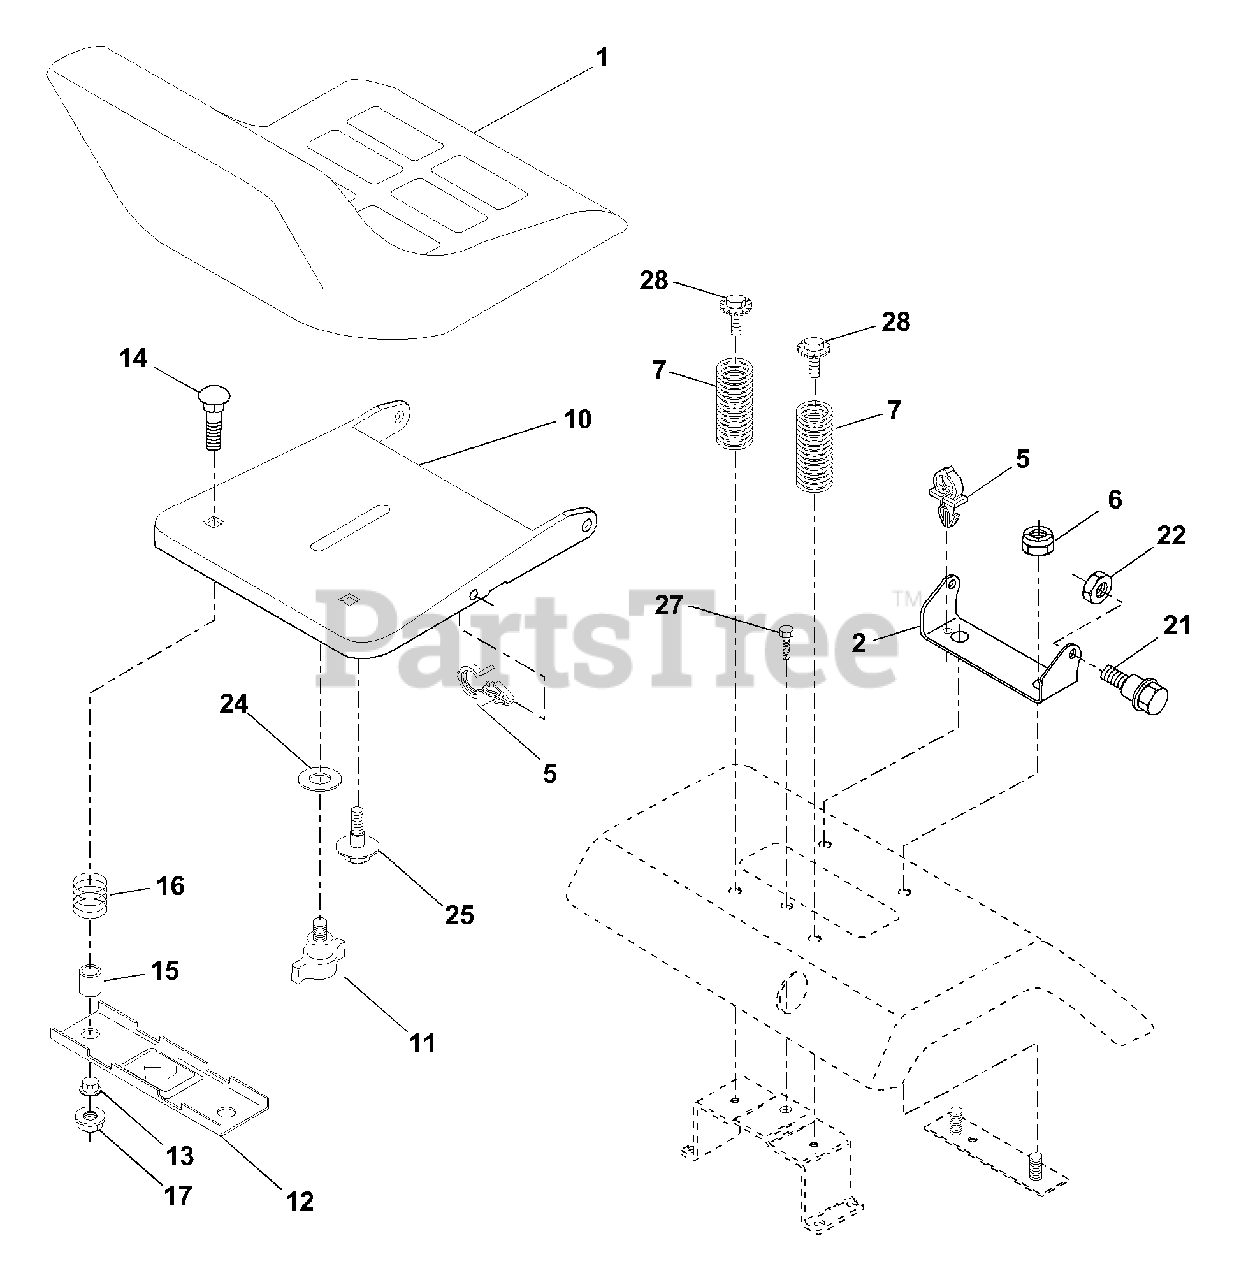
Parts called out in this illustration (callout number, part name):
1	Seat
2	Bracket Pivot Seat 8 720
5	Clip Push-In
6	Nut Hex w/Ins. 3/8-16 Unc
7	Spring Seat Cprsn 2 250 Blk Zi
10	Pan Seat
11	Knob Seat Adj Wingnut
12	Bracket Mounting Switch
13	Bushing Snap Blk Nyl 50 Id
14	Bolt Rdhd Sqnk 1/4-20x1-1/2
15	Spacer Split 28 x .88 Zinc
16	Spring Cprsn Plate
17	Nut Lock 1/4 Lge Flg Gr 5 Zinc
21	Bolt Shoulder 5/16-18 Unc
22	Nut Hex Lock W/Ins 5/16-18
24	Washer 17/32 X 1-3/16 X 12 Ga.
25	Bolt Shoulder 5/16-18 X 62
27	Screw Thdrol 3/8-16 x 1/2 Ty-tt
28	Bolt 5/16-18unc x 3/4 W/Sens
